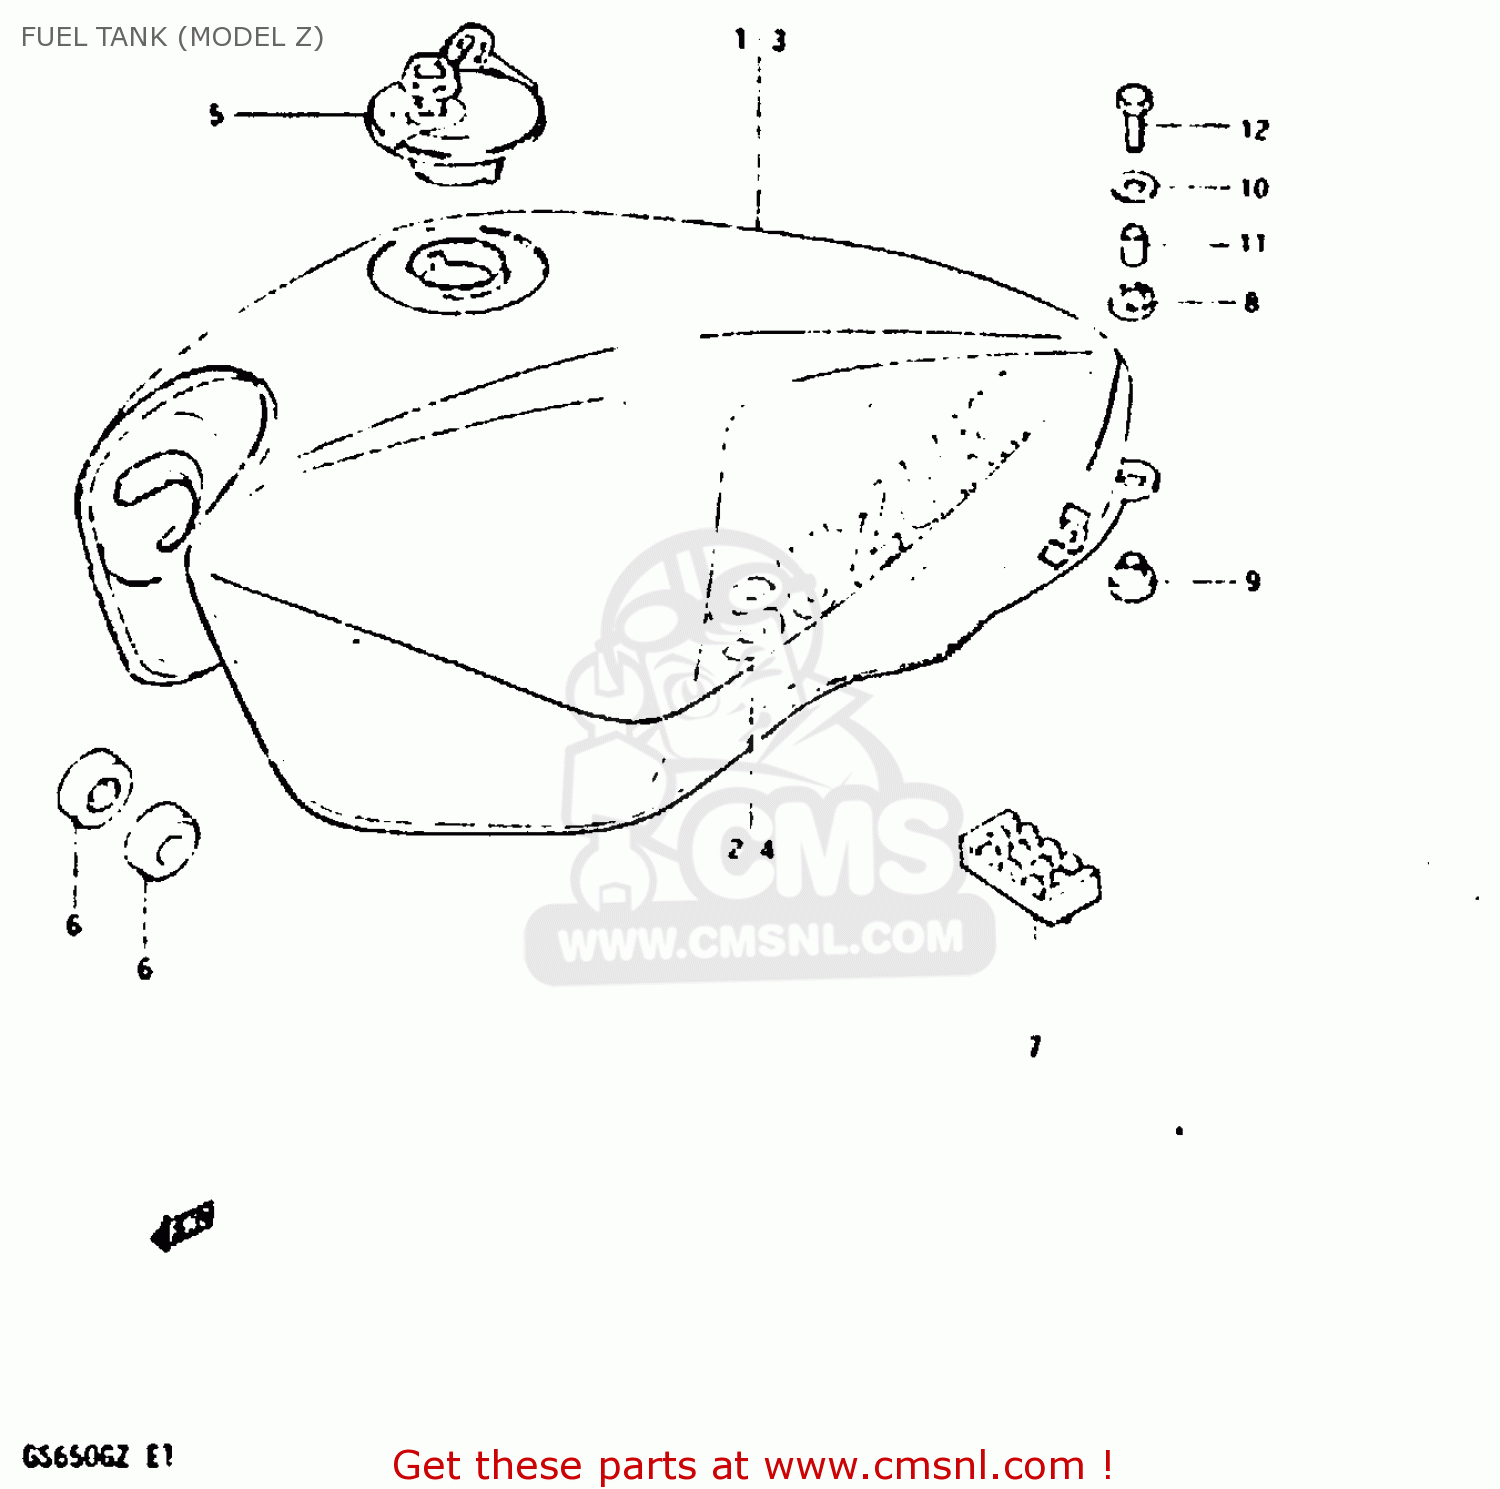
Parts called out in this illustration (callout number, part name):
1	TANK ASSEMBLY,FUEL
2	EMBLEM
3	TANK ASSEMBLY,FUEL
4	EMBLEM
5	CAP SET,FUEL TANK
6	CUSHION
7	CUSHION,FUEL TANK CTR
8	CUSHION
9	CUSHION
10	WASHER (6.5X24X1.6)
11	SPACER
12	BOLT
